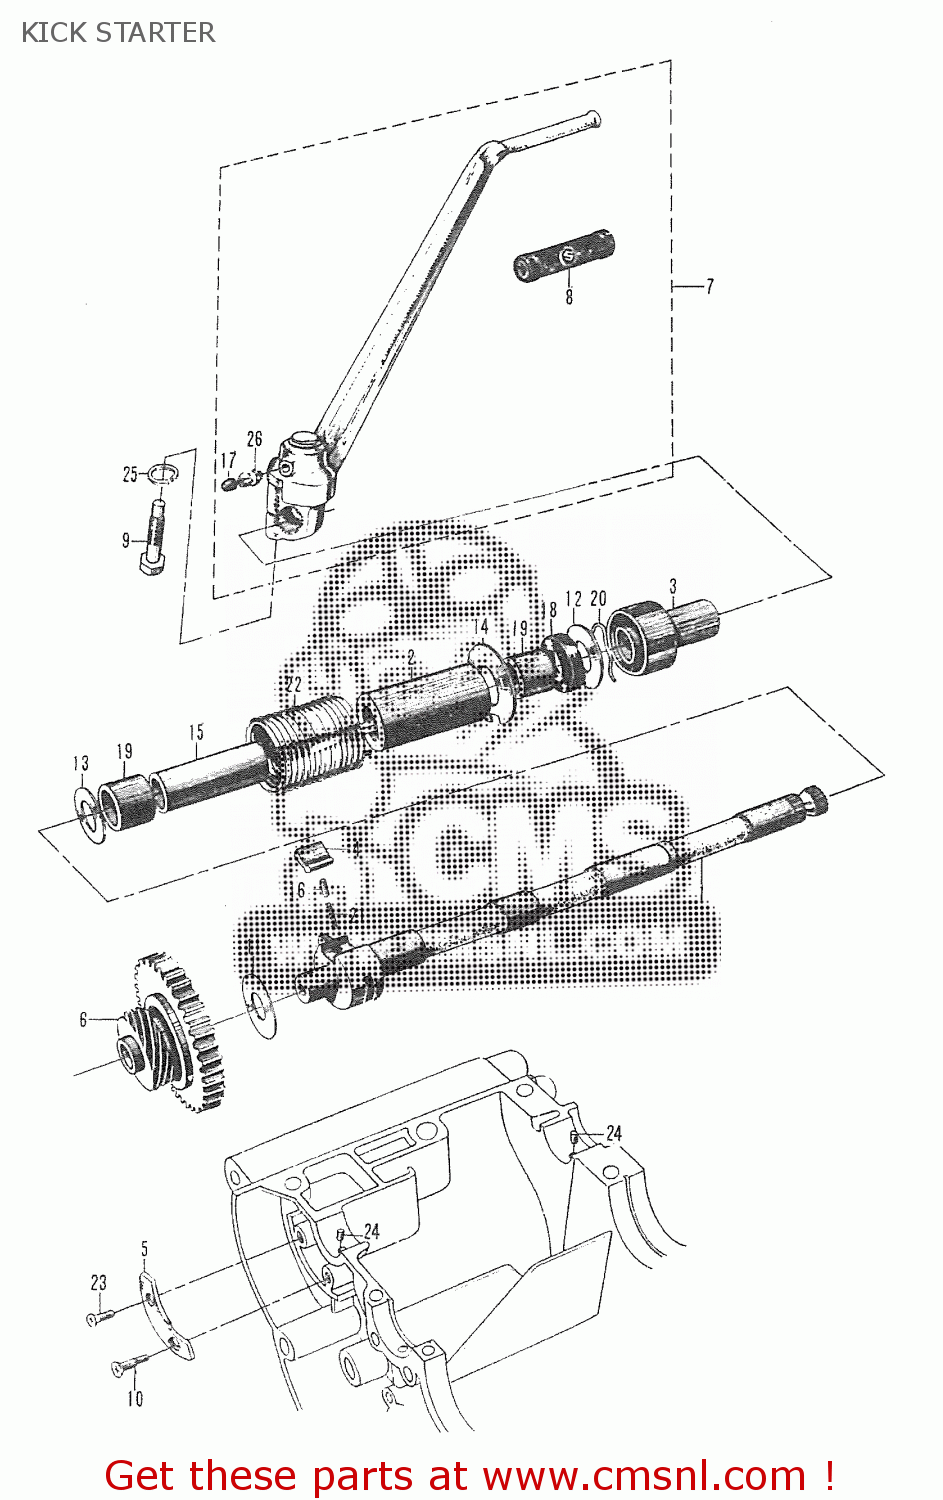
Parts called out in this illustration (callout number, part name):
1	KICK STARTER SHAFT
2	GUIDE,KICK SHAFT SPRING
3	KCIK STARTER SHAFT BUFFER
4	STARTER,KICK
5	STOPPER,KICK STARTER
6	KICK STARTER PINION
7	KICK STARTER LEVER ASS'Y
8	RUBBER,KICK STARTER PEDAL
9	BOLT(10X37.5)
10	SCREW(6X19)
11	WASHER(13X31.5X1.5)
12	WASHER
13	WASHER(16X30X1)
14	WASHER
15	KICK STARTER SHAFT RETURN SPRING GUIDE SPACER
16	PIN
17	GREASE NIPPLE CAP
18	OIL SEAL
19	BUSHING
20	SPRING,RETAINER
21	SPRING
22	SPRING
23	CROSS HEAD SCREW
24	DOWEL PIN
25	LOCK WASHER
26	GREASE NIPPLE
